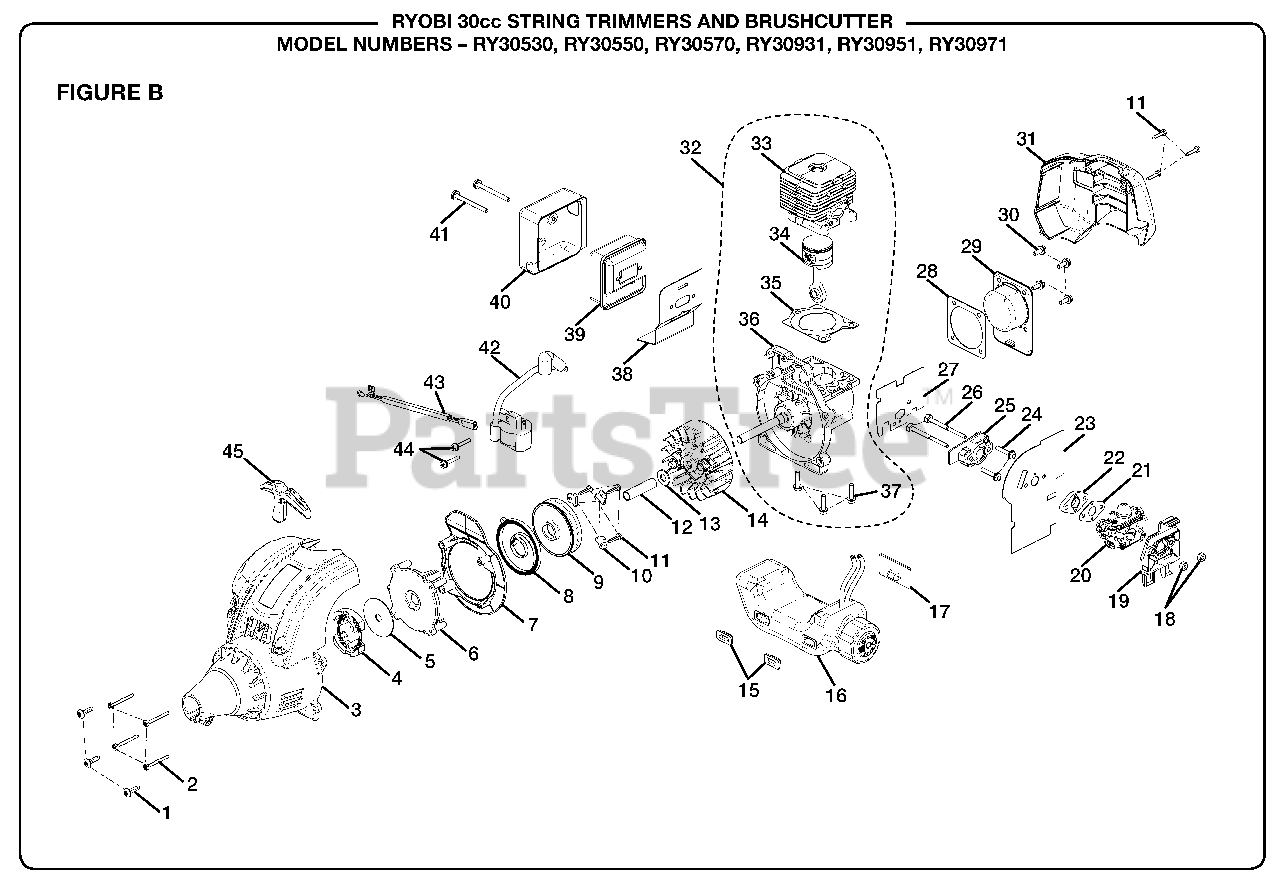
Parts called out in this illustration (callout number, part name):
1	Screw
2	Screw
3	Starter Housing Assembly
4	Clutch Assembly
6	Starter Retaining
7	Baffle Plate
8	Spring & Container
9	Pulley Assembly
10	Pulley Retainer
11	Screw
13	Washer
14	Rotor Assembly
15	Bumper
16	Fuel Tank & Cap Assembly
18	Lock Nut
19	Air Filter Base
20	Carburetor Assembly
21	Carburetor Gasket
22	Spacer
23	Carburetor Gasket
24	Screw
26	Screw
27	Heat Dam Gasket
28	Crankcase Gasket
29	Crankcase Cover
30	Pan Head Screw
31	Rear Housing
32	Short Block Assembly
33	Cylinder
34	Piston w/Rod Assembly
35	Cylinder Gasket
36	Crankcase Assembly
37	Screw
38	Muffler Gasket
39	Muffler Assembly
40	Heat Shield
41	Screw
42	Ignition Module
43	Electrical Wire Assembly
44	Screw
45	Starter Grip
